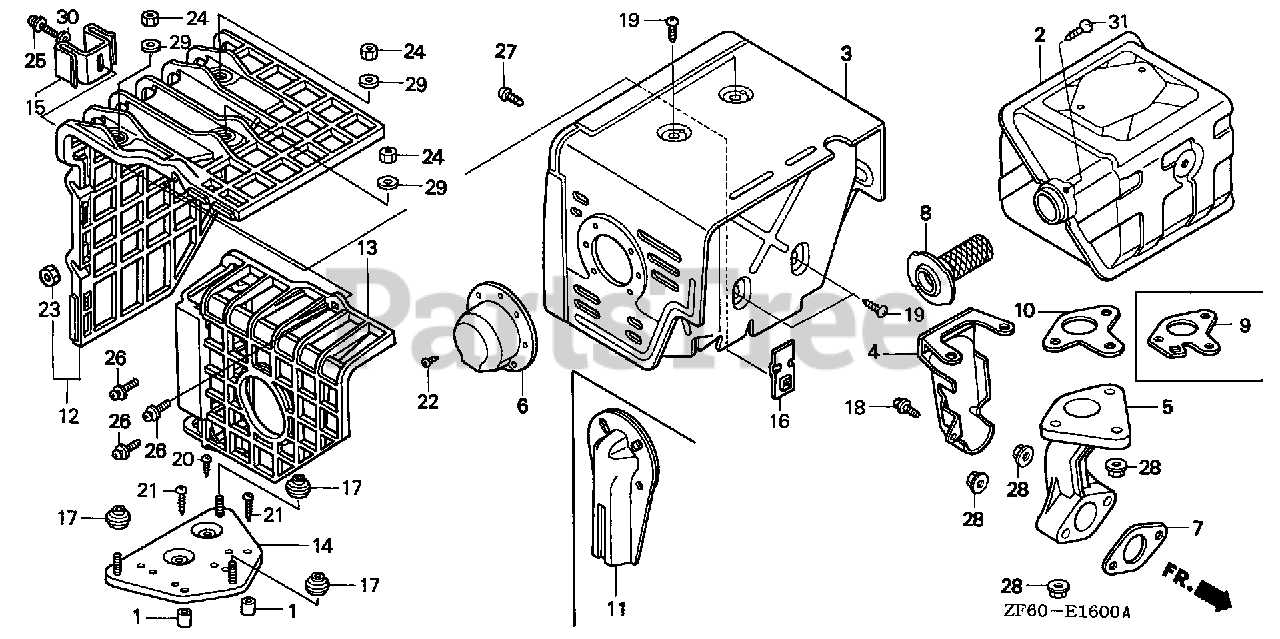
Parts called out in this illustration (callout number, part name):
2	MUFFLER (100DB)
3	PROTECTOR, MUFFLER
4	PROTECTOR, EX. PIPE
6	CAP, MUFFLER
7	GASKET, EX. PIPE
8	ARRESTER, SPARK
9	GASKET, MUFFLER (ARRESTER) (NIPPON LEAKLESS)
18	BOLT, FLANGE (6X12) (CT200)
19	SCREW, TAPPING (5X8)
22	SCREW, TAPPING (4X6)
27	SCREW, TAPPING (6X10)
28	NUT, FLANGE (8MM)
31	SCREW, TAPPING (5X8)
31	SCREW, TAPPING (4X6)
